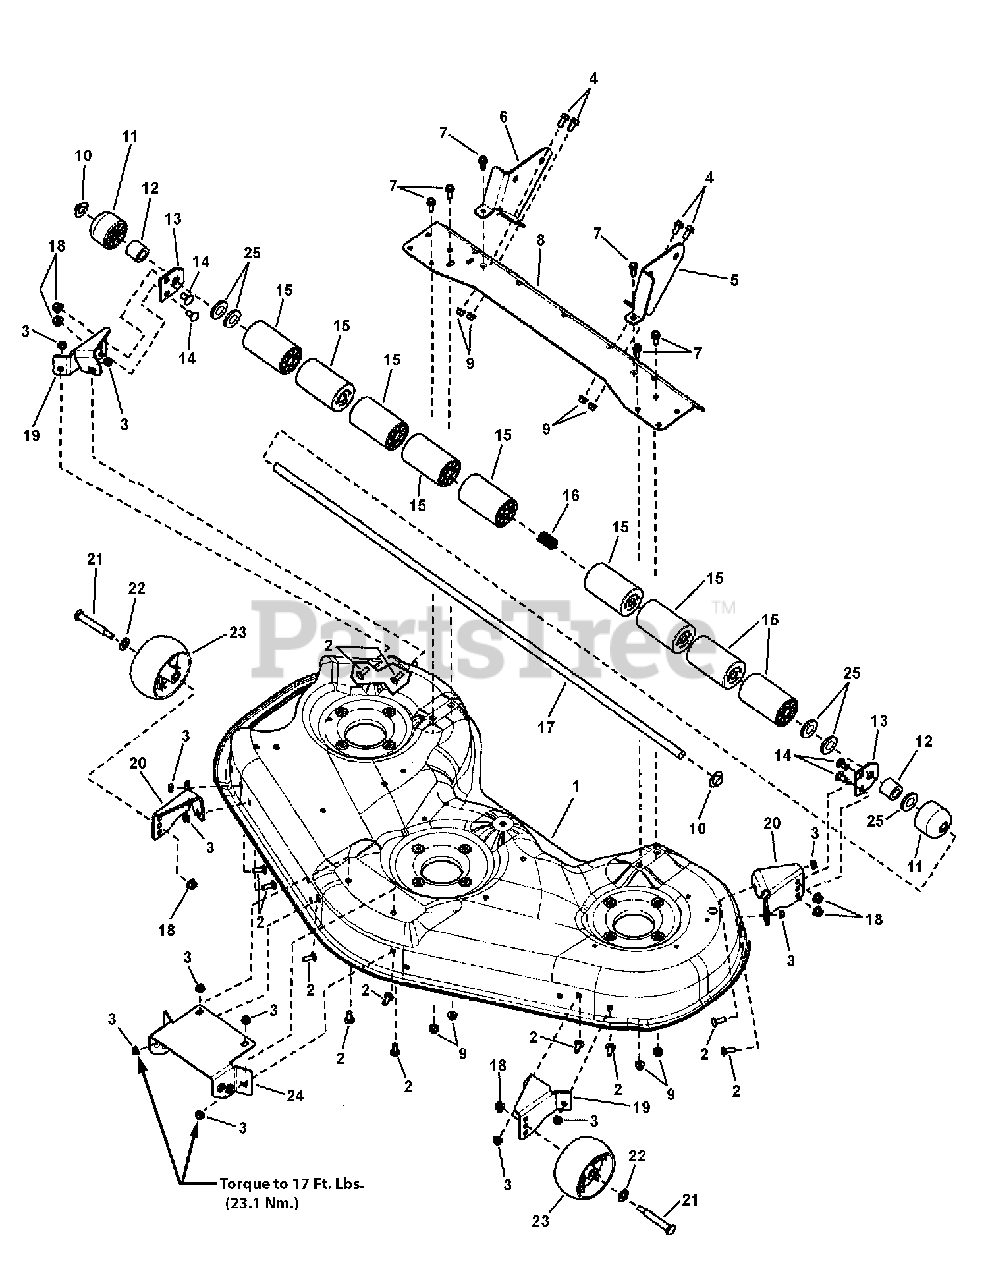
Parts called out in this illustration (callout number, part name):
1	HOUSING, 46" Mower
2	BOLT, 5/16-18 x 7/8" Round Head Short Square Neck, GR 5, Black
3	NUT, 5/16-18 Hex Flange Lock, Small - Black
4	SCREW, 5/16-18 x 3/4" Hex Flange Lock, Black
5	BRACKET, LH Rear 46/52" ZTR- Black
6	BRACKET, RH Rear 46/52" ZTR- Black
7	SCREW, 5/16-18 x 1" Hex Washer Head Self-Tap, Black
8	SUPPORT, Rear Cross
9	NUT, 5/16-18 Hex Flange Nyloc
10	PUSH NUT, .625 Shaft, Black
11	ROLLER, 2" Rounded
12	SPACER, Roller
13	BRACKET, Bar, Roller
14	BOLT, 3/8-16 x 3/4" Round Head Square Neck Carriage, YZ
15	ROLLER
16	SPRING, Compression .095 Wire Dia. x .675 ID x 1.52 Fl
17	SHAFT, Roller, 46"
18	NUT, 3/8-16 Hex Flange Esna, Black
19	BRACKET, Gauge Wheel, RH
20	BRACKET, Gauge Wheel, LH
21	SHOULDER BOLT, 3/8-16 x 3.41" .750 Thread Yellow
22	WASHER, 1/2" Flat (0.51 ID x 1.00 OD x .10 Thick) Black
23	GAUGE WHEEL, Black Poly 5" Dia.
24	HITCH, Front, 46/52 Mower
25	WASHER, 5/8" Flat
